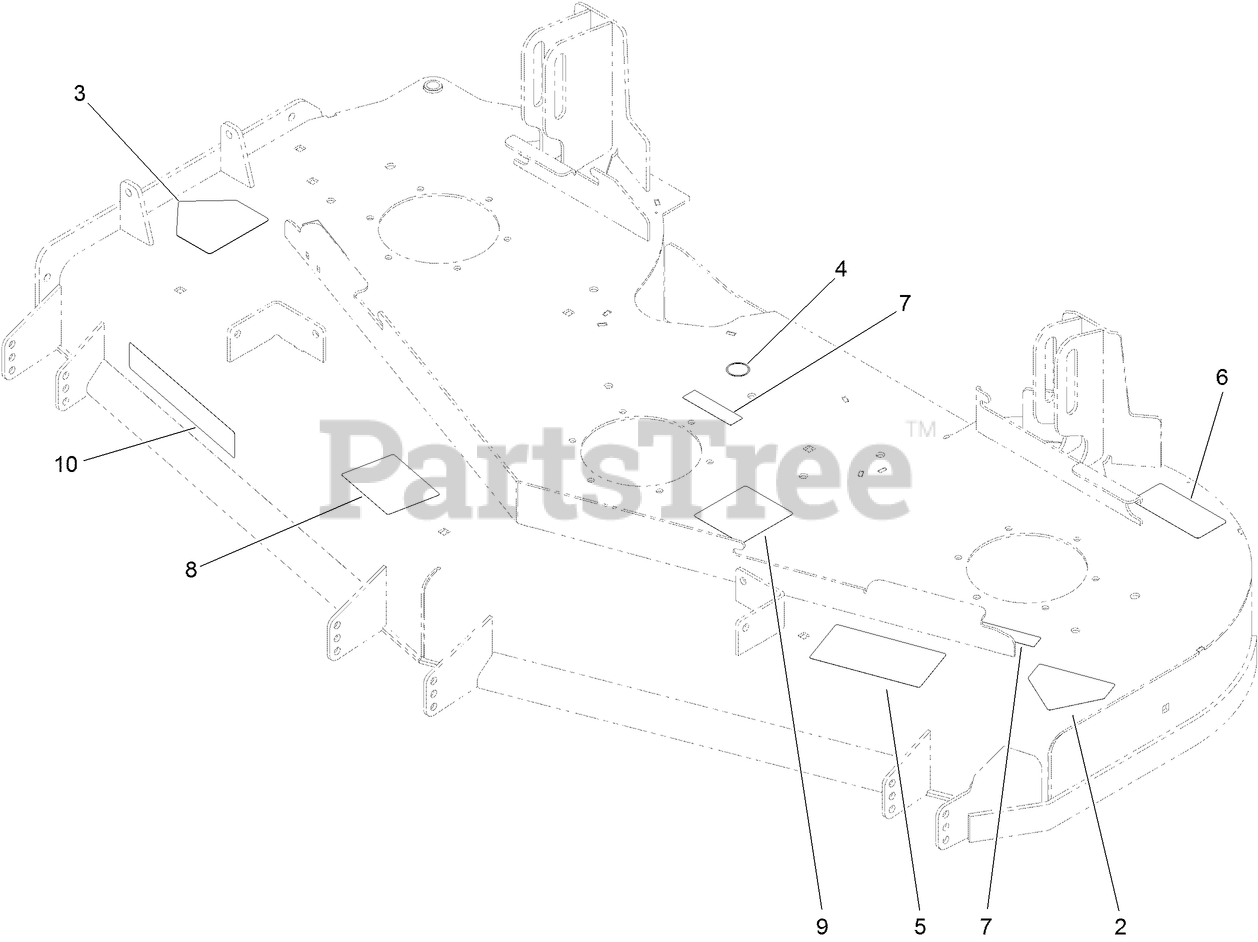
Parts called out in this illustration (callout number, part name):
2	DECAL-DANGER
3	DECAL-DANGER
4	DECAL-GREASE
5	DECAL-DANGER, THROWN OBJECT
6	DECAL-TORQUE
7	DECAL-COVER, MISSING
8	DECAL-SCALP, ANTI
9	DECAL-ROUTING, DECK BELT
